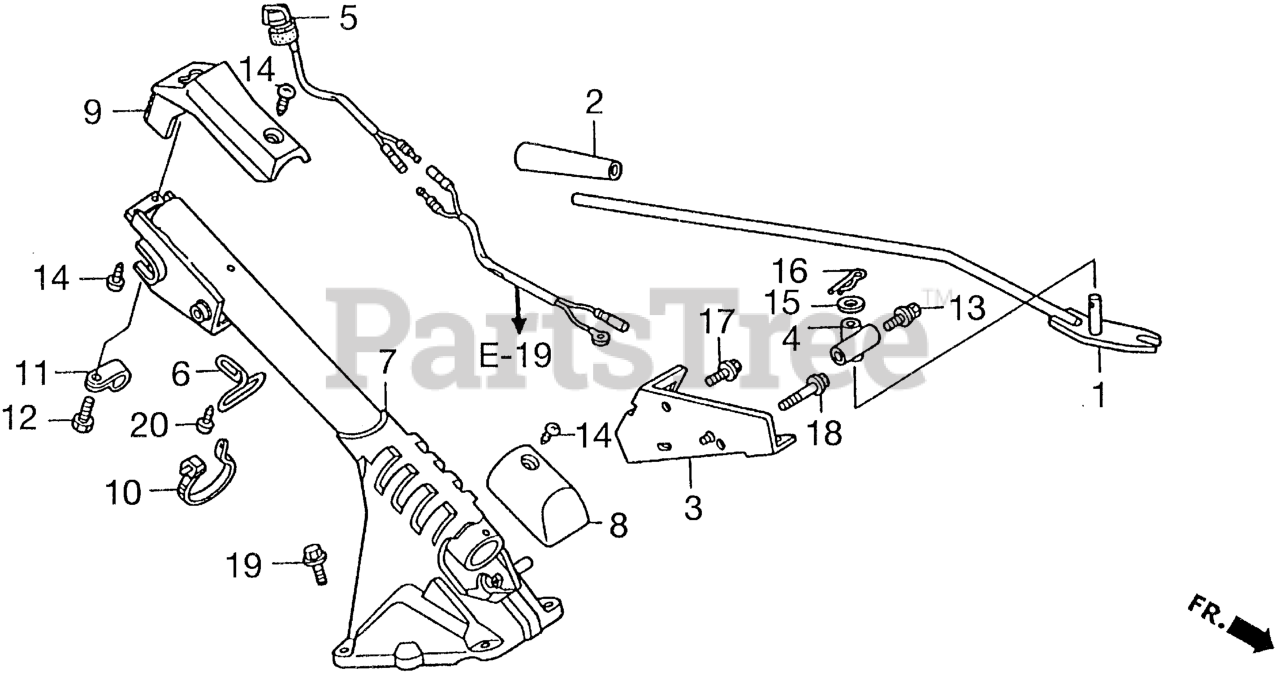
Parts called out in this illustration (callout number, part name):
3	BRACKET, CHANGE LEVER
5	SWITCH ASSY., ENGINE STOP
6	GUIDE, CABLE
7	COLUMN, HANDLE *NH105* (MAT BLACK)
8	COVER, COLUMN (LOWER)
9	COVER, HANDLE COLUMN
10	BAND, SUCTION HOSE (BLACK)
11	CLIP, WIRE HARNESS (6.3MM)
12	BOLT, HEX. (5X14)
14	SCREW, TAPPING (5X12)
17	BOLT, FLANGE (6X12) Use up to Engine SN 1543277.
18	BOLT, FLANGE (6X30)
19	BOLT, FLANGE (8X16) Use from Engine SN 1000016.
20	SCREW, TAPPING (5X10)
